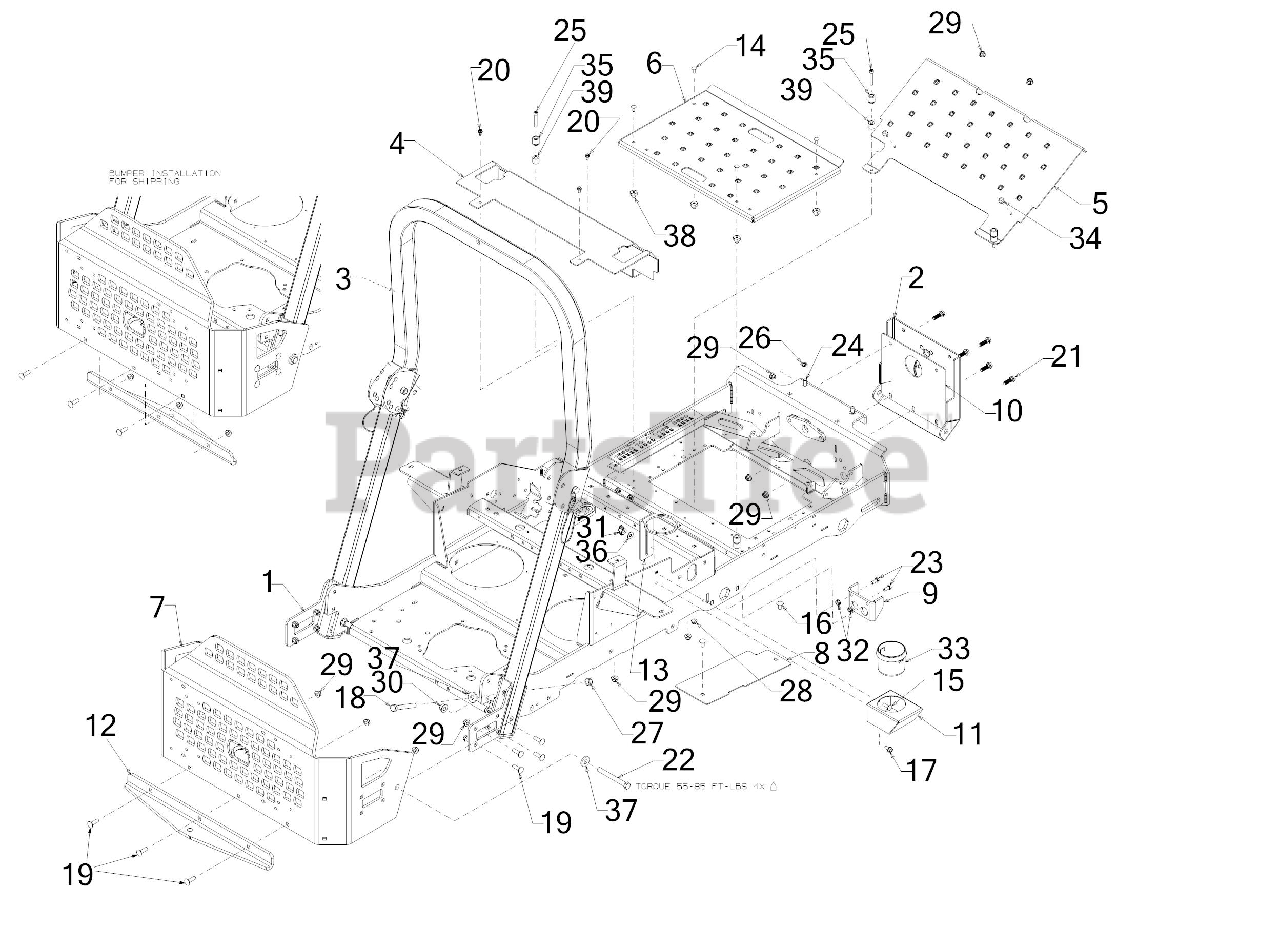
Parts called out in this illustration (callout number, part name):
1	FRAME ASSEMBLY
2	AXLE COVER ASSEMBLY
3	FOLDING ROPS ASSEMBLY
4	SEAT BOX COVER
5	FRONT FOOT PAN
6	LAP BAR FLOOR PANEL TRAY
7	REAR BUMPER
8	SEAT PANEL COVER(RH)
9	FRONT DECK LIFT MOUNTING BRACKET
10	FRONT AXLE PLATE
11	LOWER CUP HOLDER
12	HITCH BRACKET
13	UPPER CUP HOLDER BRACKET
14	CARRIAGE BOLT 1/4-20 x .62
15	CARRIAGE BOLT 5/16-18 x 1.00
16	CARRIAGE BOLT 3/8-16 x .750 GR5
17	SCREW 5/16-18 x .750
18	SCREW 1/2-20 x 3.50 GR5
19	CARRIAGE BOLT 3/8-16 X1.25 GR5
20	SCREW 1/4-20 X.500
21	SCREW 3/8-16 x .875 GR5
22	SCREW 1/2-13 x 4.5 GR 5
23	SCREW 5/16-18 x .75 GR5
24	CARRIAGE BOLT 3/8-16 x 1.00 GR5
25	SCREW 5/16-18X1.75 GR5
27	HEX NUT
28	FLANGE LOCK NUT 5/16-18
31	WING NUT 5/16-18
32	FLANGE NUT
34	BUMPER, .62 DIA x .3
35	RADIAL BUMPER
36	FLAT WASHER
37	FLAT WASHER .531 x 1.25 x .181
38	SHOULDER SPACER
